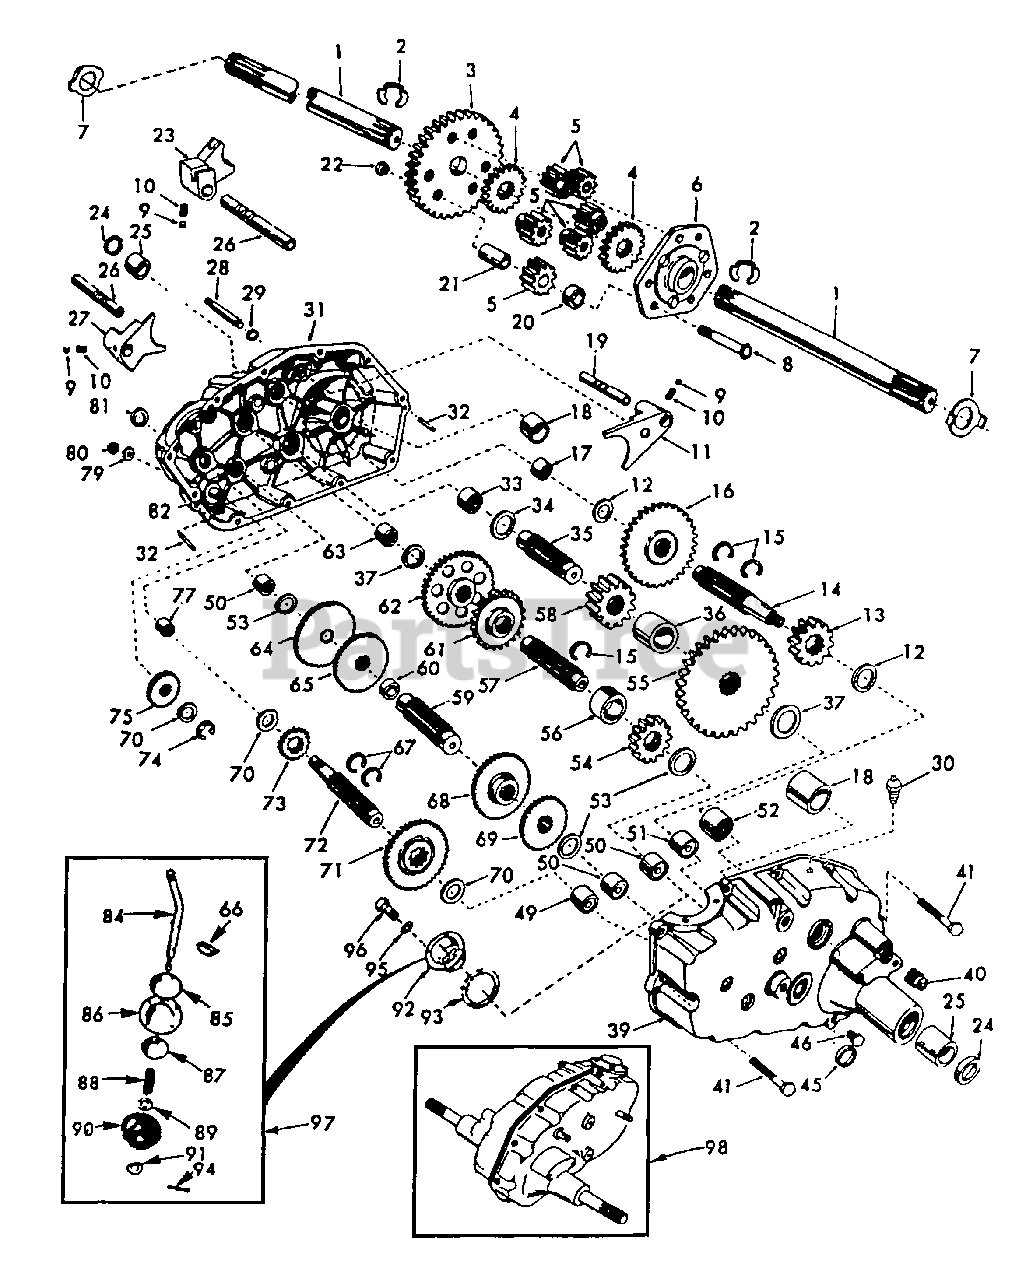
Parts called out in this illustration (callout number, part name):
1	Axle Shaft
2	Retaining Ring
3	Final Drive Gear
4	Differential Gear
5	Differential Pinion
6	Differential Carrier
7	Axle Thrust Washer
8	Bolt, Hex Head 3/8-24 x 3-1/4 (1" Thread Length)
9	Steel Ball (AYP part number)
10	Spring Shift Fork Detent (AYP part number)
11	Shift Fork, High-Low Range
12	Thrust Bearing Race
13	4th Reduction Pinion
14	Shaft, Brake
15	Snap Ring, Crescent Type
16	High-Low Range Gears
17	Needle Bearing
18	Sintered Iron Bearing (AYP part number)
19	Shift Fork Shaft, High-Low Range
20	Differential Pinion Spacer
21	Differential Pinion Bushing
22	Gripco Centerlock Nut 3/8-24
23	Shift Fork, R.H.
24	Oil Seal
25	Sintered Iron Bearing (AYP part number)
26	Shift Fork Shaft
27	Shift Fork, L.H.
28	Shift Shaft, High-Low Range
29	Oil Seal
30	Pressure Relief Valve
31	Gearcase, Reverse idler Shaft and Bearings, R.H. (AYP part number)
32	Dowel Pin
33	Needle Bearing
34	Thrust Bearing Race
35	4th Reduction Gear Shaft
36	4th Reduction Gear Spacer (AYP part number)
37	Thrust Bearing Race
39	Gearcase and Bearings, L.H. (AYP part number)
40	Pipe Plug 1/2-14 N.P.T.
41	Bolt, Hex 5/16-18 UNC x 1-1/4
45	Oil Seal
46	Pipe Plug 1/4-18 N.P.T. (AYP part number)
49	Needle Bearing
50	Needle Bearing
51	Needle Bearing
52	Needle Bearing
53	Thrust Bearing Race
54	3rd Reduction Pinion, Low
55	4th Reduction Gear
56	3rd Reduction Pinion Spacer
57	2nd Reduction Gear Shaft
58	Final Drive Pinion
59	1st Reduction Gear Shaft
60	1st Reduction Shaft Spacer
61	3rd Reduction Pinion High
62	2nd Reduction Gear
63	Needle Bearing
64	Low Speed Gear and 2nd Reduction Pinion Cluster
65	Reverse Gear
66	Key, Hi-Pro 1/8 x 17/32
67	Klip Ring
68	Intermediate Speed Gear
69	High Speed Gear
70	Thrust Bearing Race
71	Intermediate and High Speed Cluster Pinions
72	Input Shaft (AYP part number)
73	Low Speed Pinion
74	E-Ring
75	Reverse Idler Gear
77	Needle Bearing
79	Sealing Washer
80	Nut, Hex, Jam 7/16-20
81	Oil Seal
82	Reverse Idler Shaft
84	Gearshift Lever, Bent
85	Gearshift Cap
86	Gearshift Ball Cover and Pin
87	Shift Lever Guide Ball, Keyed
88	Spring
89	Washer 15/32 x 15/16 x 16 Gauge
90	Shift Mechanism Seal
91	Washer 9/16 x 15/16 x 12 Gauge
92	Gearshift Gate and Reinforcement
93	Shift Ball Cover Gasket
94	Cotter Pin 1/8 x 3/4
95	Washer, Lock 5/16
96	Bolt, Hex Head 5/16-18 UNC x 7/8
97	Gearshift Lever Assembly
98	Transaxle, 6 Speed, Complete Assembly (AYP part number)
